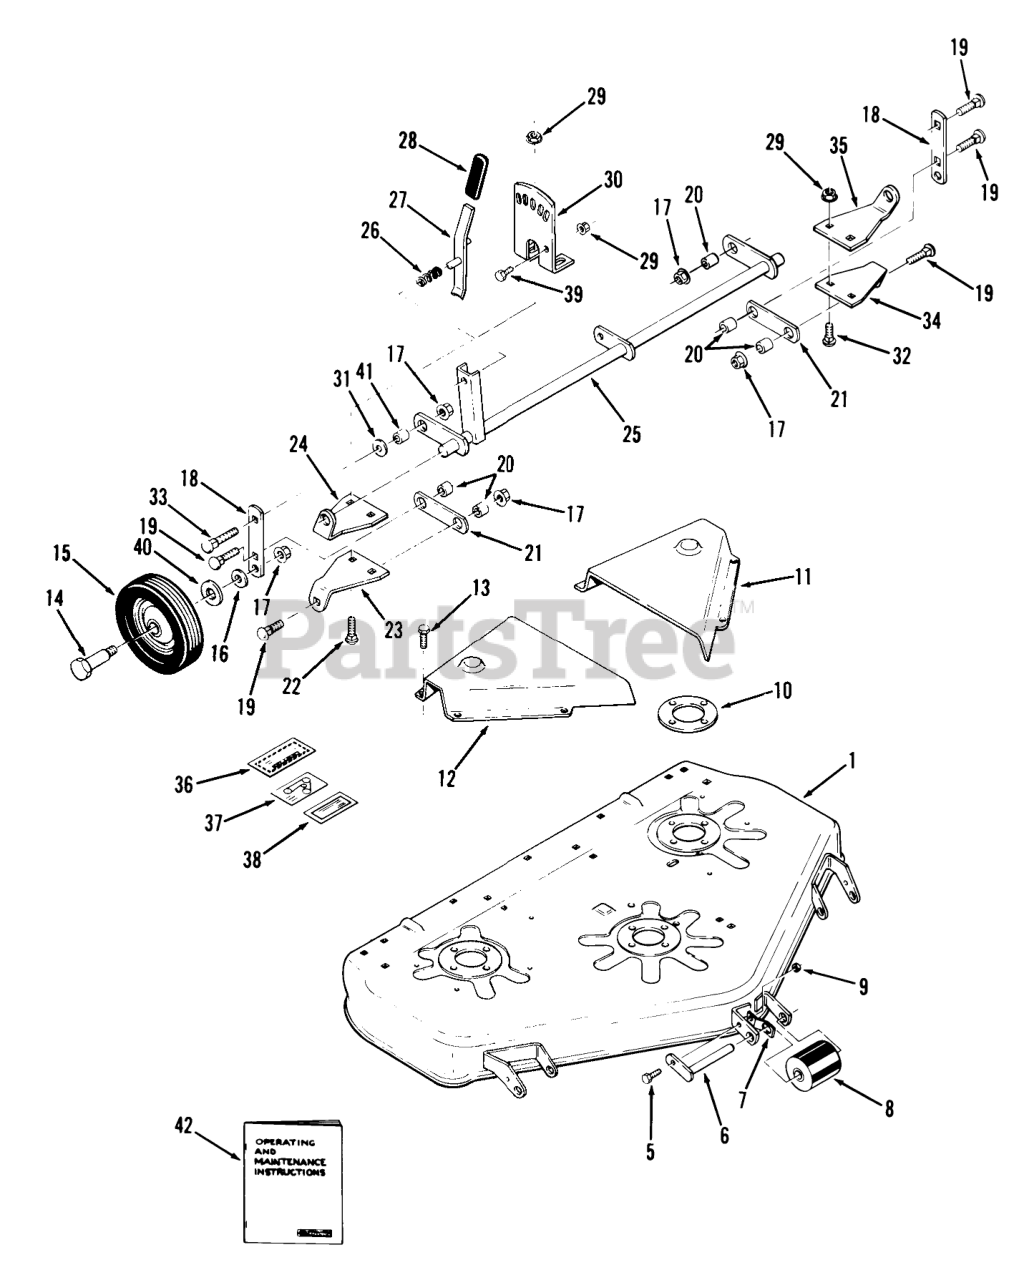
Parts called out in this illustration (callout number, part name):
10	PLATE-SPINDLE
13	Bolt
14	BOLT-SHOULDER
20	SPACER
26	SPRING-COMPRESSION
31	WASHER
37	DECAL-HEIGHT & BELT
40	WASHER-FLAT
42	Operating and Maintenance Instructions
